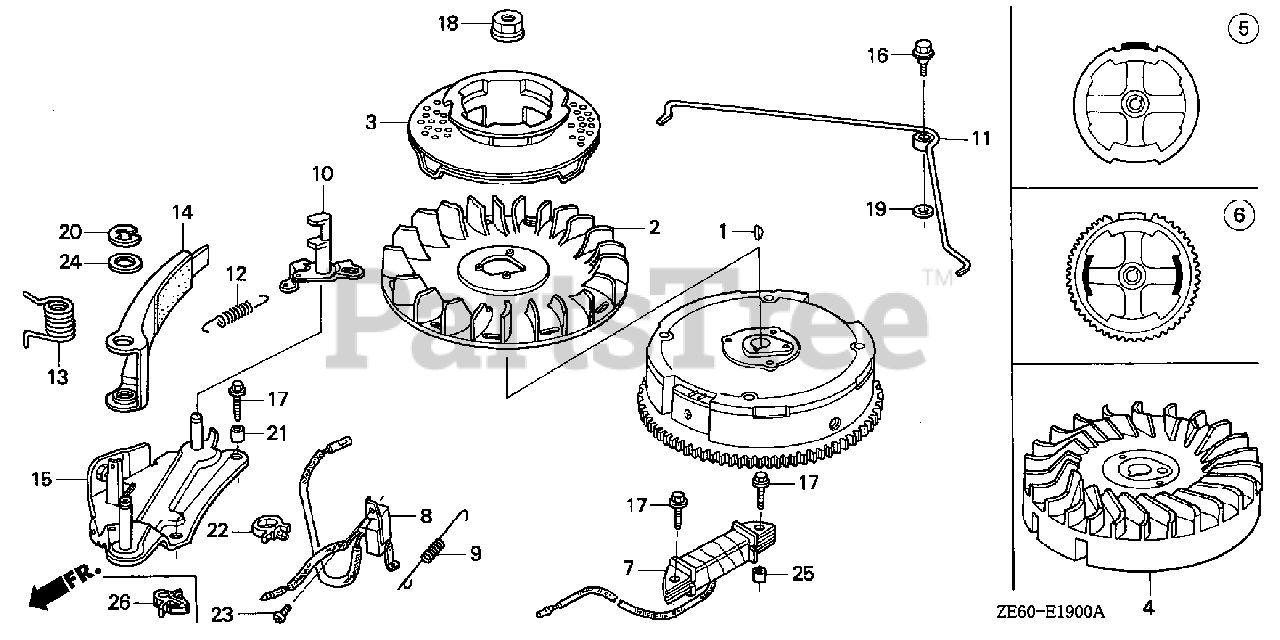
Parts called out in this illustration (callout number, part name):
1	KEY, SPECIAL WOODRUFF (25X18)
2	FAN, COOLING
3	PULLEY, STARTER
5	FLYWHEEL (STD)
5	FLYWHEEL
18	NUT, SPECIAL (14MM)
